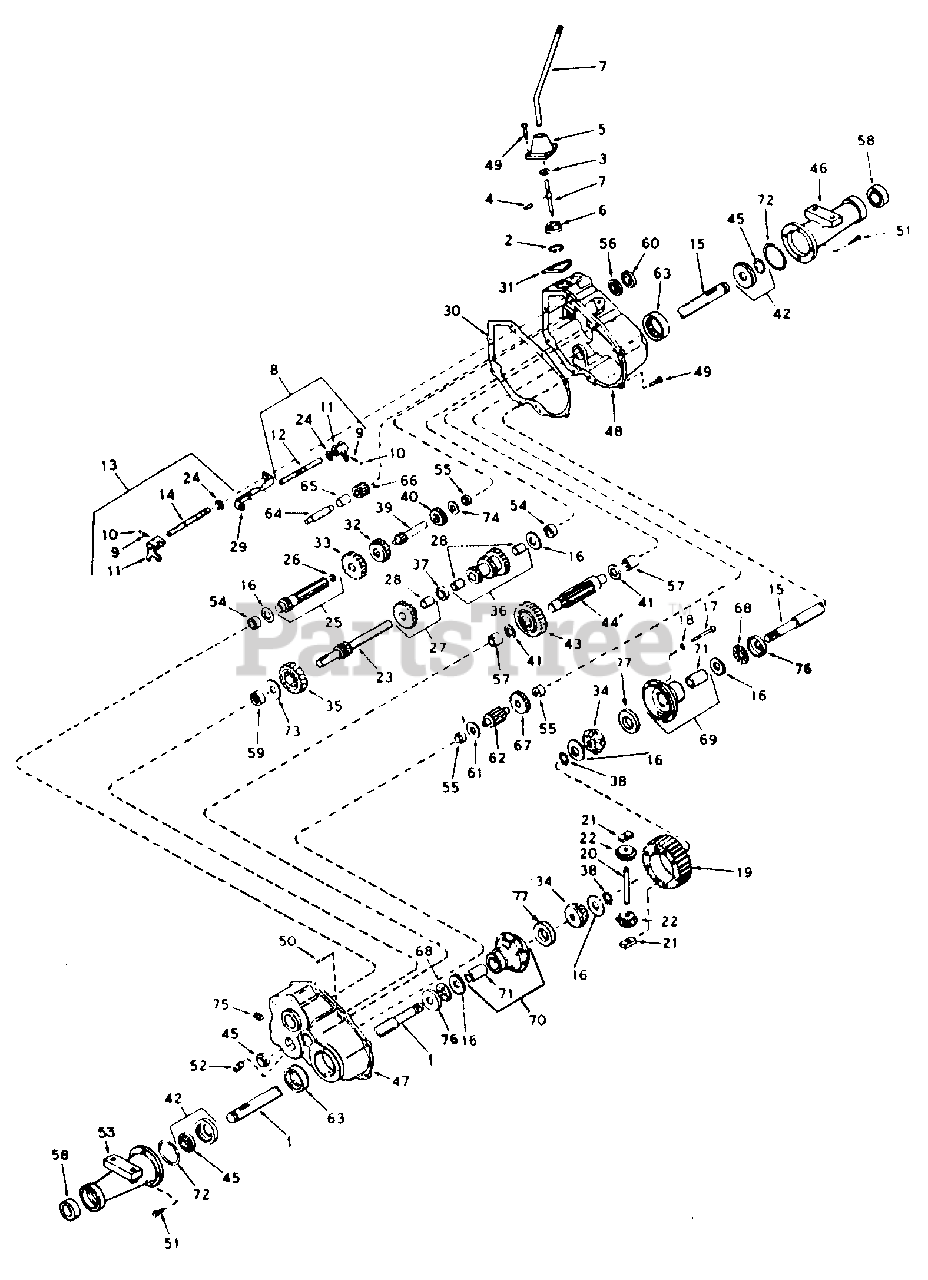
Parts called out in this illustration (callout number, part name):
2	Ring, Snap
3	Ring, Quad
5	Housing, Shift Lever
6	Retainer, Shift Lever
7	Lever, Shift
8	Rod Assy, Shift
10	Ball, Steel
11	Fork, Shifter
12	Rod, Shifter 3rd & 4th
13	Rod Assy, Shift
14	Rod, Shifter 1st & 2nd
16	Washer, Thrust
17	Bolt, 1/4 X 2-1/2 Pln Type 8
18	Washer, 1/4 Heavy Lock
20	Pin, Drive
23	Shaft, Brake Gear
24	Ring, Snap
25	Shaft Assy, Pinion
26	Bearing Assy, Needle
27	Gear Assy, Cluster
29	Stop, Shifter
30	Gasket, Case to Cover
31	Gasket, Shifter Lever Housing
32	Gear, Shift 3rd & 4th
33	Gear, Shifting 1st, 2nd & Rev.
34	Gear, Bevel
35	Gear, Idler
36	Gear, Cluster
38	Ring, Snap
39	Shaft, Input
40	Gear, Input Shaft Spur
41	Washer, Thrust
42	Cap w/Seal
43	Gear, Output
44	Pinion, Output
46	Housing, Axle, RH
47	Cover Assy, Transaxle
48	Case Assy, Transaxle
49	Screw, 1/4-20 X 3/4 Flanged
50	Pin, Dowel
51	Bolt, 5/16 X 1 Pln Type 5
52	Plug, Magnetic Drain
53	Housing, Axle, LH
54	Bearing, Needle
55	Bearing, Needle
56	Bearing, Ball
57	Bearing, Needle
58	Bearing Assy, Ball
59	Bearing, Needle
62	Shaft, Pinion
63	Bearing, Needle
64	Shaft, Reverse Idler
65	Spacer, Reverse Idler
67	Gear, Spur -22T
68	Bearing, Thrust
69	Carrier Assy, Differential, RH
70	Carrier Assy, Differential, LH
71	Bushing, Carrier
73	Washer, Thrust
74	Washer, Thrust
75	Plug, Pipe
76	Bearing, Thrust Race
